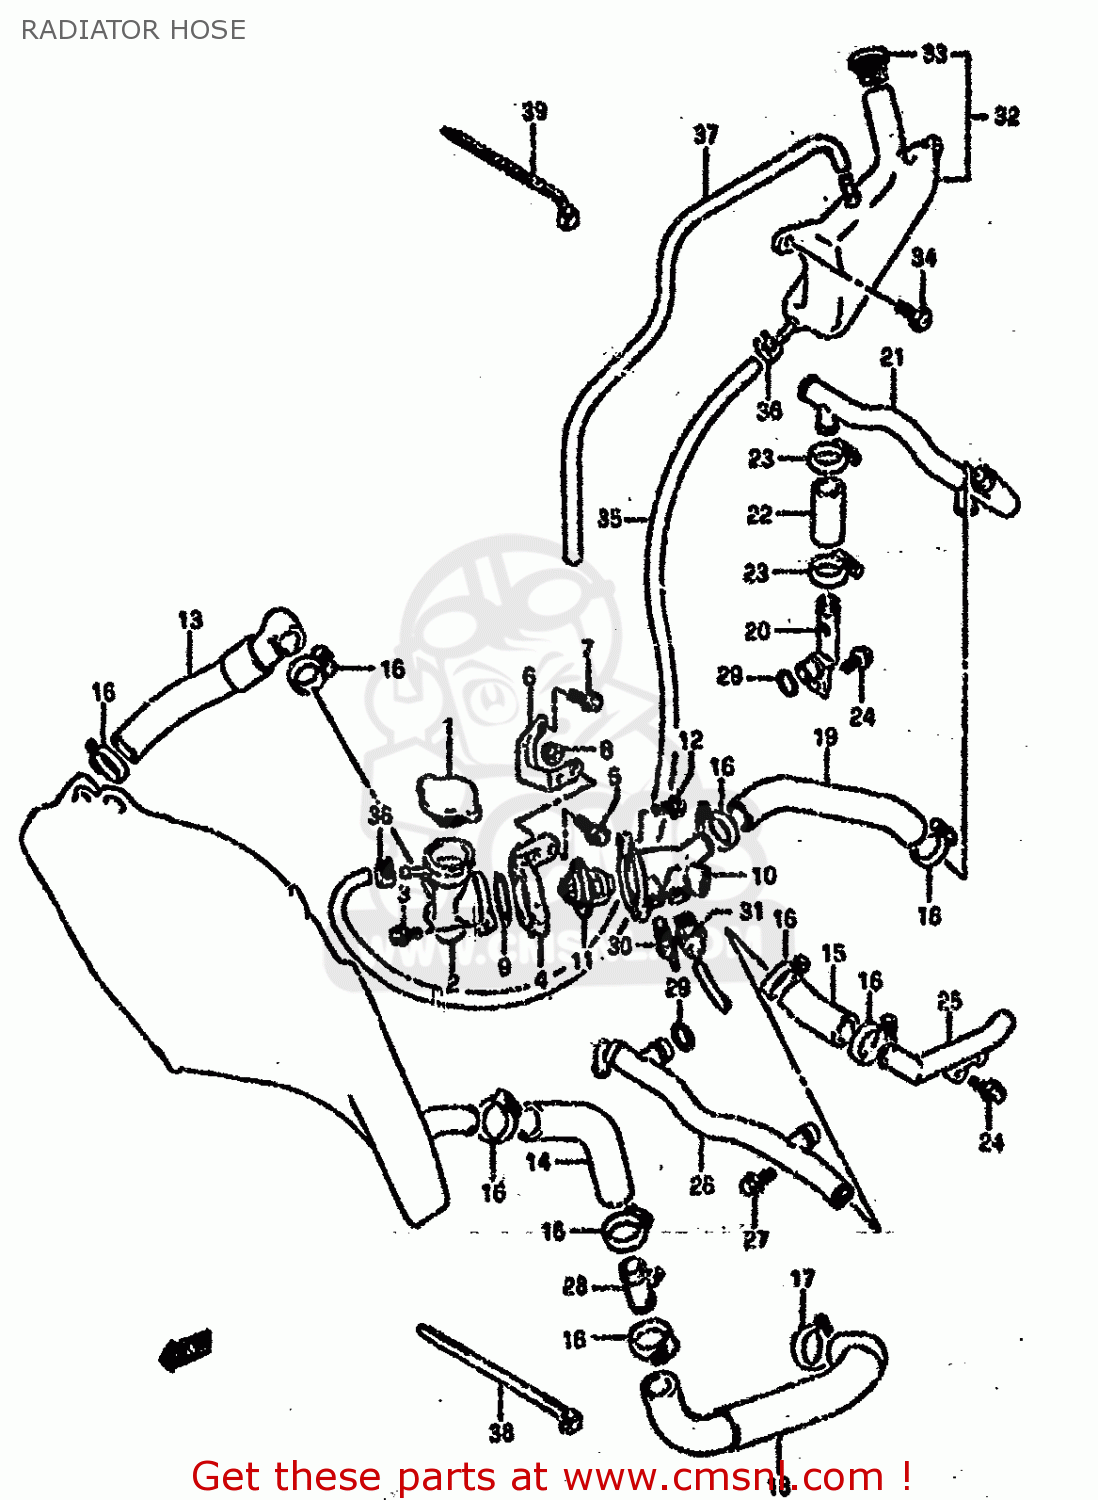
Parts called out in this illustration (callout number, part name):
1	CAP,RADIATOR
2	CONDUCTION,RADIATOR
3	BOLT
4	BRACKET,CONDUCTION
5	BOLT
6	BRACKET,CONDUCTION BRAKE
7	BOLT
8	NUT
9	O RING(D:2.4,ID:43.2)
10	CONNECTOR,THERMOSTAT INLET
11	THERMOSTAT,WATER
12	BOLT
13	HOSE,RADIATOR INLET
14	HOSE,RADIATOR OUTLET
15	HOSE,WATER
16	CLAMP
17	CLAMP
18	HOSE,WATER PUMP INLET
19	HOSE,HEAD OUTLET
20	PIPE,HEAD OUTLET
21	PIPE,HEAD OUTLET NO.2
22	HOSE,WATER
23	CLAMP
24	BOLT
25	PIPE,CYLINDER SIDE
26	PIPE,CYLINDER INLET
27	BOLT
28	UNION,HOSE JOINT
29	O RING(D:3.2,ID:17.8)
30	GAUGE ASSY,WATER TEMP
31	SWITCH COMP,RADIATOR FAN
32	TANK ASSY,RESERVOIR
33	CAP,RESERVOIR TANK
34	SCREW(6X20)
35	HOSE,RESERVOIR TANK INLET
36	CLIP
37	HOSE,RESERVOIR TANK OVERFLOW
38	CLAMP
39	CLAMP L:165
